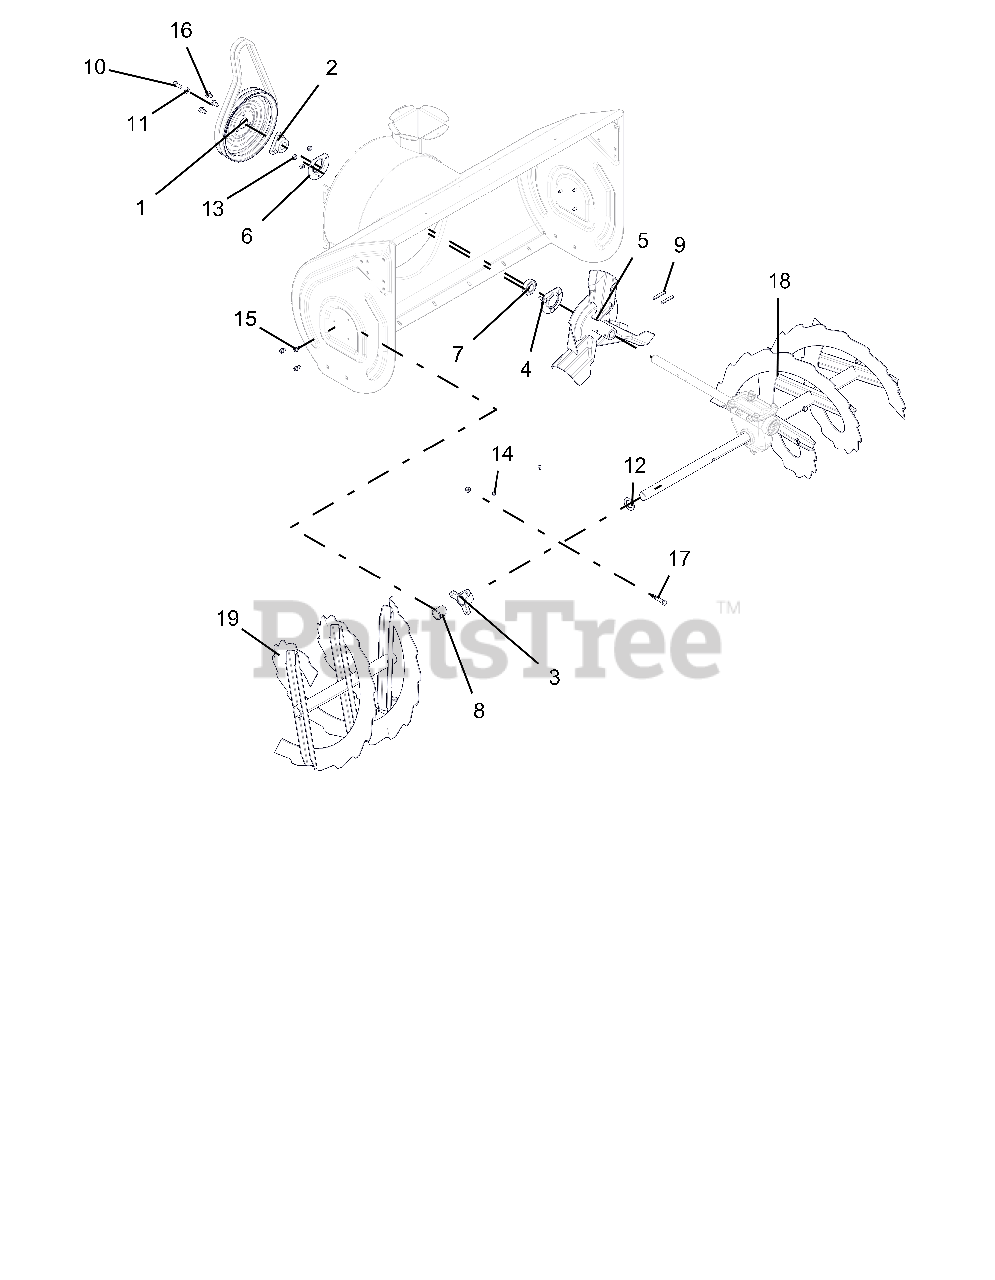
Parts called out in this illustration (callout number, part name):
1	PULLEY, SPIN FORM DUAL GROOVE
2	PULLEY HUB, D-BORE .87 PRO
3	BUSHING, RAKE SHAFT 1"
4	BEARING FLANGE
5	IMPELLER, 3 BLADE-14"
6	BEARING FLANGE
7	BRG-BALL .876X1.75X.50 RSTFP
8	BSHG-FLG SPLIT NYLINER 1.0" HP
9	PIN-ROLL .250X1.75
10	BLT-HEX .31-24X.75 YWZC GR5
11	WSHR-LK .312X.097 HVY YWZC
12	WSHR-FL-STL 1.010X1.505X.062YZ
13	@NUT-LK-CTR .25-20 YWZC
14	ZERK,FITTING .25X.125 DRIVE IN
15	SCR-TAP .25-20X.50 HWH TR YWZ
16	@SCR-TAP .31-18X.50 HWH TR YWZ
17	SHEAR BOLT SERVICE ASSEMBLY
18	RAKE, LH-36" (1 ID X 15.75 OD)
19	RAKE, RH-36"(1 ID X 15.75 OD)
